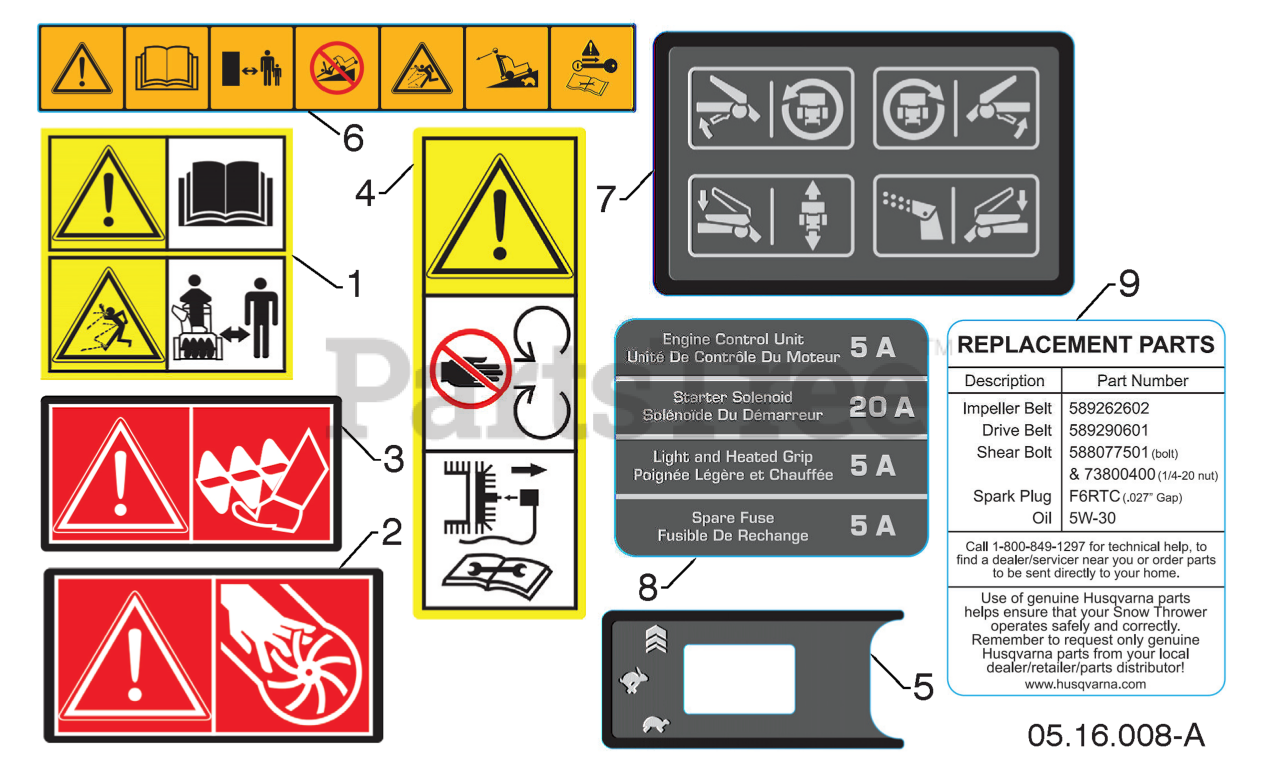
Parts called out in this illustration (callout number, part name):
1	DECAL.AUGER."
2	DECAL.CHUTE.SAFETY.EU/SC.17
3	DECAL.AUGER.SAFETY.
4	DECAL.BELT.GUARD.
5	DECAL SNOW CONSOLE GRAPHIC DEC
6	DECAL SNOW CONSOLE GRAPHIC DEC
7	DECAL SNOW CONSOLE GRAPHIC DEC
8	DECAL SNOW BATTERY BOX GRAPHIC
9	DECAL SNOW BATTERY BOX GRAPHIC
